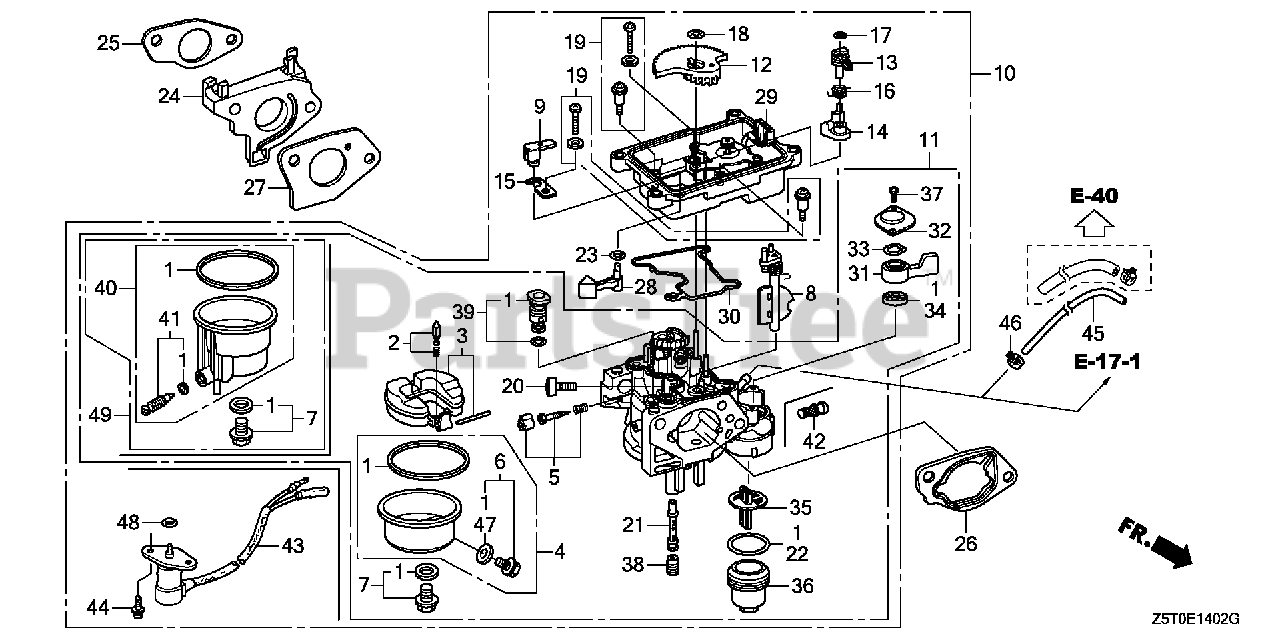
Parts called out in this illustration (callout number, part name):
1	GASKET SET (INCLUDES 16173-001-004)
2	VALVE SET, FLOAT
4	CHAMBER SET, FLOAT
5	SCREW SET, PILOT
6	SCREW SET, DRAIN
9	ARM, MANUAL START
10	CARBURETOR ASSY. (BE92G A)
11	CARBURETOR SET
12	GEAR, MIDDLE
13	ARM, CHOKE
14	LEVER, CHOKE CONTROL
16	SPRING, TORSION COIL
17	CLIP, SPECIAL
18	CLIP, SPECIAL
20	SCREW, STOP
21	NOZZLE, MAIN
22	GASKET, FUEL STRAINER CUP
24	INSULATOR, CARBURETOR
25	GASKET, CARBURETOR INSULATOR
26	SPACER, CARBURETOR
27	GASKET, CARBURETOR
28	LEVER, MANUAL START
29	CASE, MOTOR
31	LEVER, PETCOCK
32	PLATE, LEVER SETTING
33	SPRING, PETCOCK LEVER
34	GASKET, PETCOCK
35	FILTER, CUP
36	CUP, FUEL STRAINER
37	SCREW, PAN (3X6)
38	JET, MAIN (#98)
38	JET, MAIN (#102)
38	JET, MAIN (#105)
39	JET SET, PILOT (#40)
47	WASHER, PLAIN (6.2X10.7 DRAIN)
